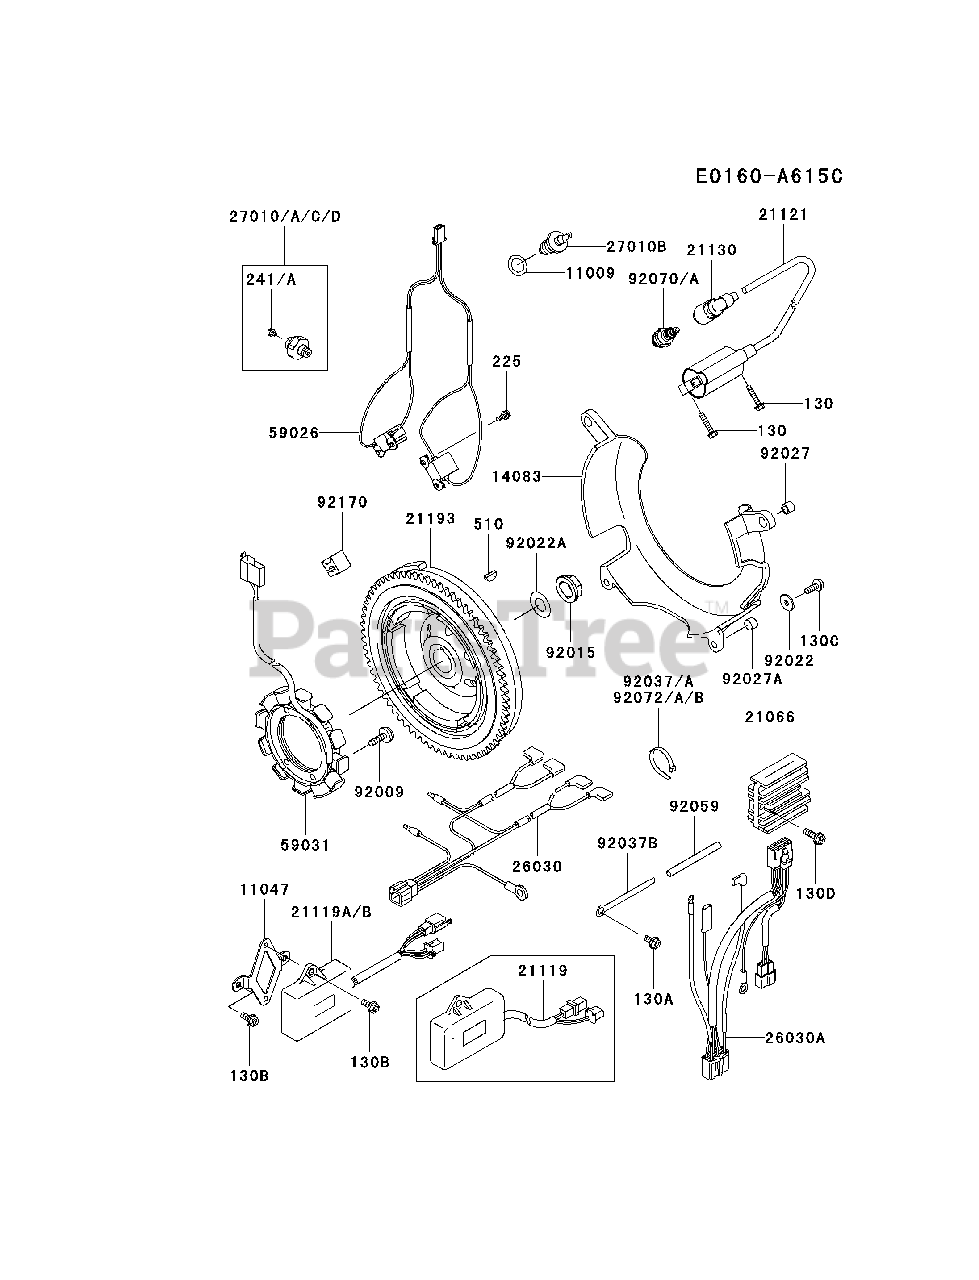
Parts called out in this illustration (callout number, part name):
130C	BOLT-FLANGED,6X16
130D	BOLT-FLANGED,6X20
225	SCREW-PAN-WSP-CROS,4X14
510	KEY-WOODRUFF
